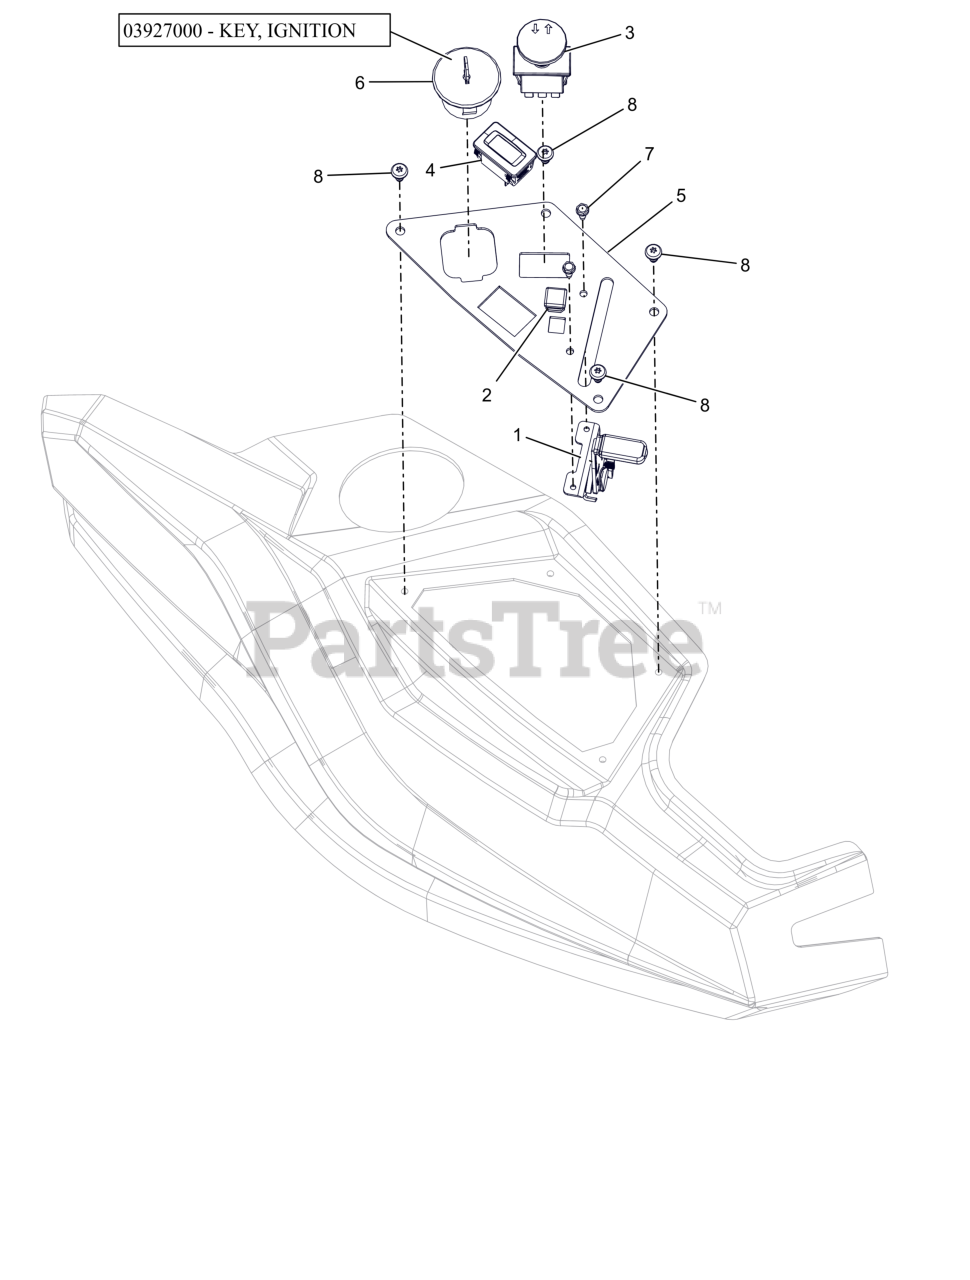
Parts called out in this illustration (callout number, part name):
1	CABLE, THROTTLE
2	PLUG, 5/8" SQ BLACK (14-20GA)
3	SWITCH, CLUTCH (YELLOW)
4	HOUR METER
5	PANEL, CONTROL (ORANGE)
6	KEYSWITCH-IGNITION 3 POS
6	KEY, 03290500 KEYSWITCH
7	SCR,TAP #10-24X.50 HWH TR ZCC
8	SCR-PAN .25-15X.50 6L H/LZB500
